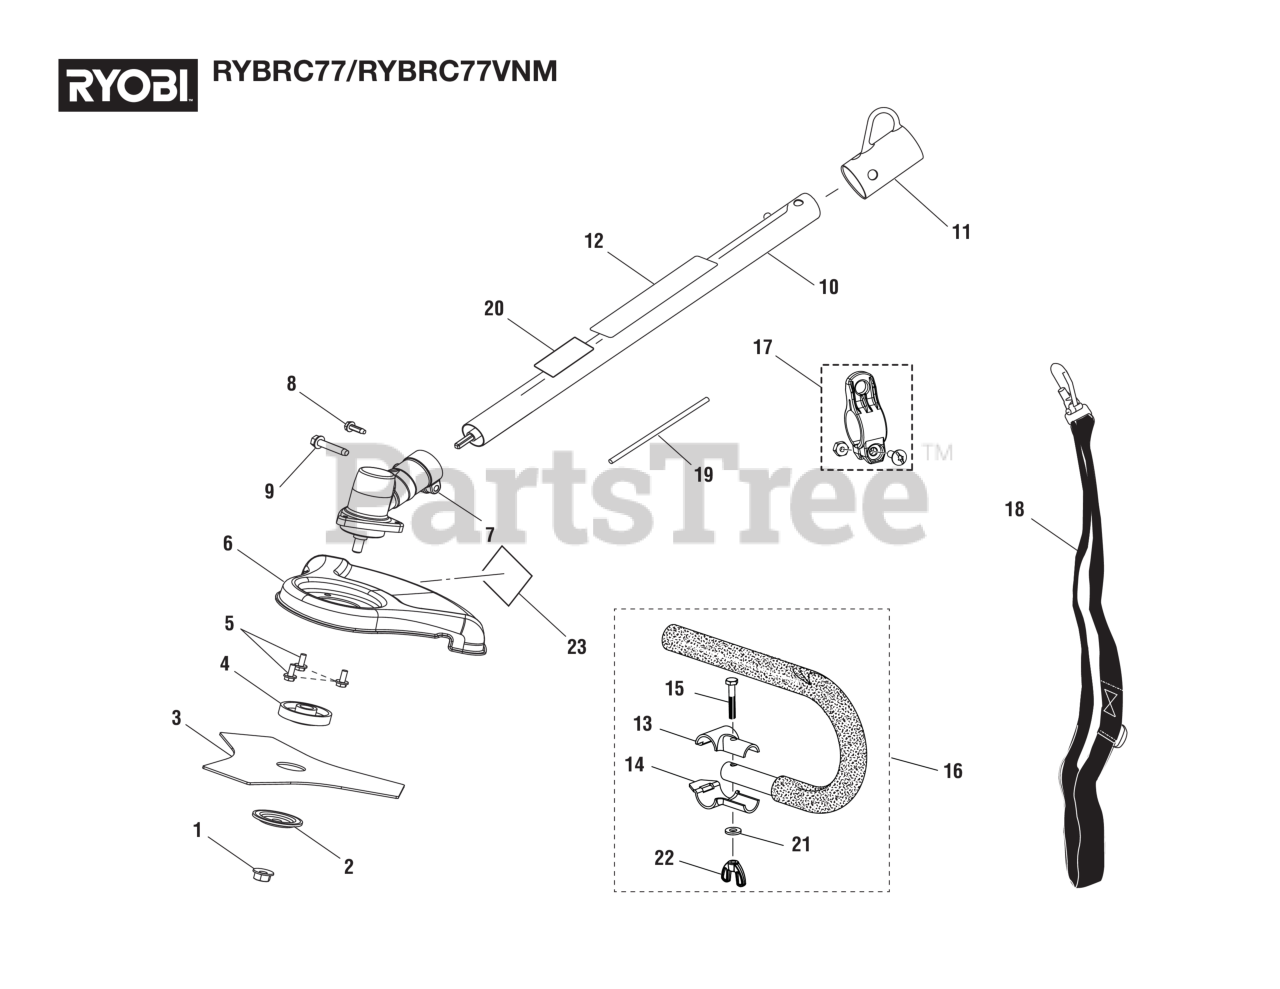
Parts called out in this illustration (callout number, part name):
1	Lock Nut (M8 x 1.25 in., Left Hand Threads)
2	CUPPED WASHER
3	BLADE (TRI-ARC(TM))
4	FLANGED WASHER
5	Screw w/Washer (10-24 x 1/2 in., Slotted Hex Hd.)
6	Brush Cutter Guard
7	Gear Case Assembly
8	Screw w/Washer (10-24 x 5/8 in., Hex Hd. T.F.)
9	Screw (1/4-20 x 1-1/4 in., Hex Washer Hd. S.T.)
10	Lower Straight Shaft Boom Assembly
11	Hanger Cap
12	Brushcutter Safety Label
13	Top "J" Handle Clamp
14	Bottom "J" Handle Clamp
15	Bolt (1/4-20 x 1-1/2 in., Hex Hd.)
16	"J" Handle and Grip
17	Strap Hanger
18	Shoulder Harness Assembly
19	Gear Head Locking Tool
20	Ryobi EXPAND-IT Label
21	Washer (ID7.25 x OD16 x 1.5t)
22	Wing Nut (1/4-20, Plastic)
23	Logo Label
